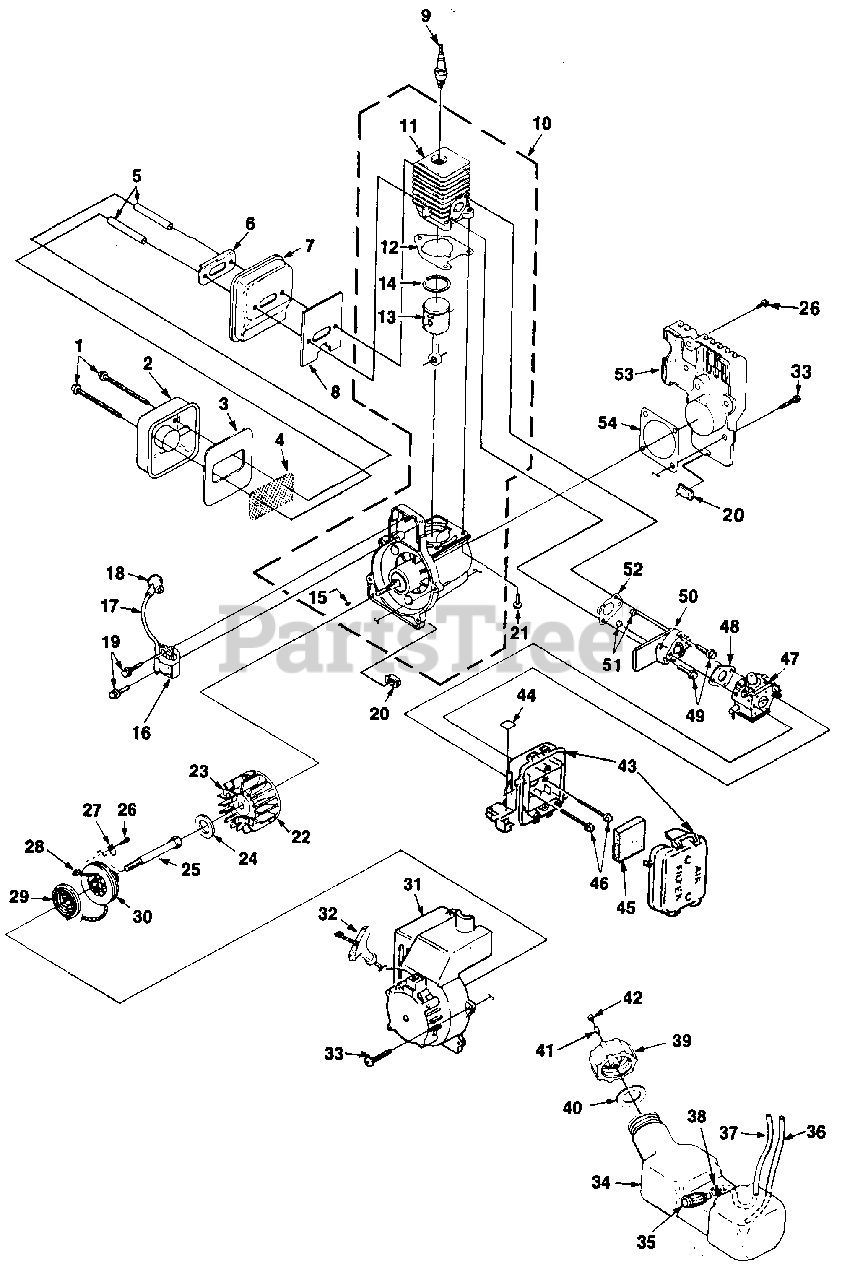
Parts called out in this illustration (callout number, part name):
1	SCREW Sems hex hd. (10-24 x 2 1/2")
2	MUFFLER- Cover
3	BAFFLE- Muffler
4	SCREEN- Spark
5	SPACER- Muffler
6	PLATE- Reinforcing
7	MUFFLER BODY
8	GASKET- Muffler
9	SPARK PLUG (Champion DJ7Y)
10	SHORT BLOCK
11	CYLINDER & GASKET
12	GASKET- Cylinder
13	PISTON & ROD ASSY.
14	RING- Piston
15	KEY- Woodruff
16	MODULE- Ignition (Phelon)
17	LEAD- Hi-Tension
18	TERMINAL- Hi-Tension
19	SCREW- Taptite (8-32 x 1")
20	BUMPER- Rubber
21	SCREW- Taptite (10-24 x 3/4")
22	ROTOR & STARTER PAWL
23	STARTER PAWL KIT
24	WASHER
25	EXTENSION- Shaft
26	SCREW- Plastite (10 x 1/2")
27	BRACKET Retaining
28	ROPE- Starter
29	SPRING & CONTAINER
30	PULLEY- Starter
31	ENGINE HOUSING & DECAL KIT
32	GRIP- Starter rope
33	SCREW (10-24 x 1")
34	FUEL TANK
35	FILTER- Fuel
36	TUBING- Rubber (8")
37	TUBING- Rubber (8")
38	CLAMP- Wire
39	FUEL CAP
40	GASKET- Fuel cap
41	VALVE- Filter
42	CAP- Filter
43	AIR FILTER BOX
44	DECAL- Choke
45	FILTER- Air
46	SCREW- (10-24 x 2 1/4")
47	CARBURETOR (Walbro)
48	GASKET- Carburetor
49	SCREW- Taptite (10-24 x 1")
50	HEAT DAM
51	NUT- (10-24)
52	GASKET- Heat dam
53	CRANKCASE COVER
54	GASKET- Crankcase cover
